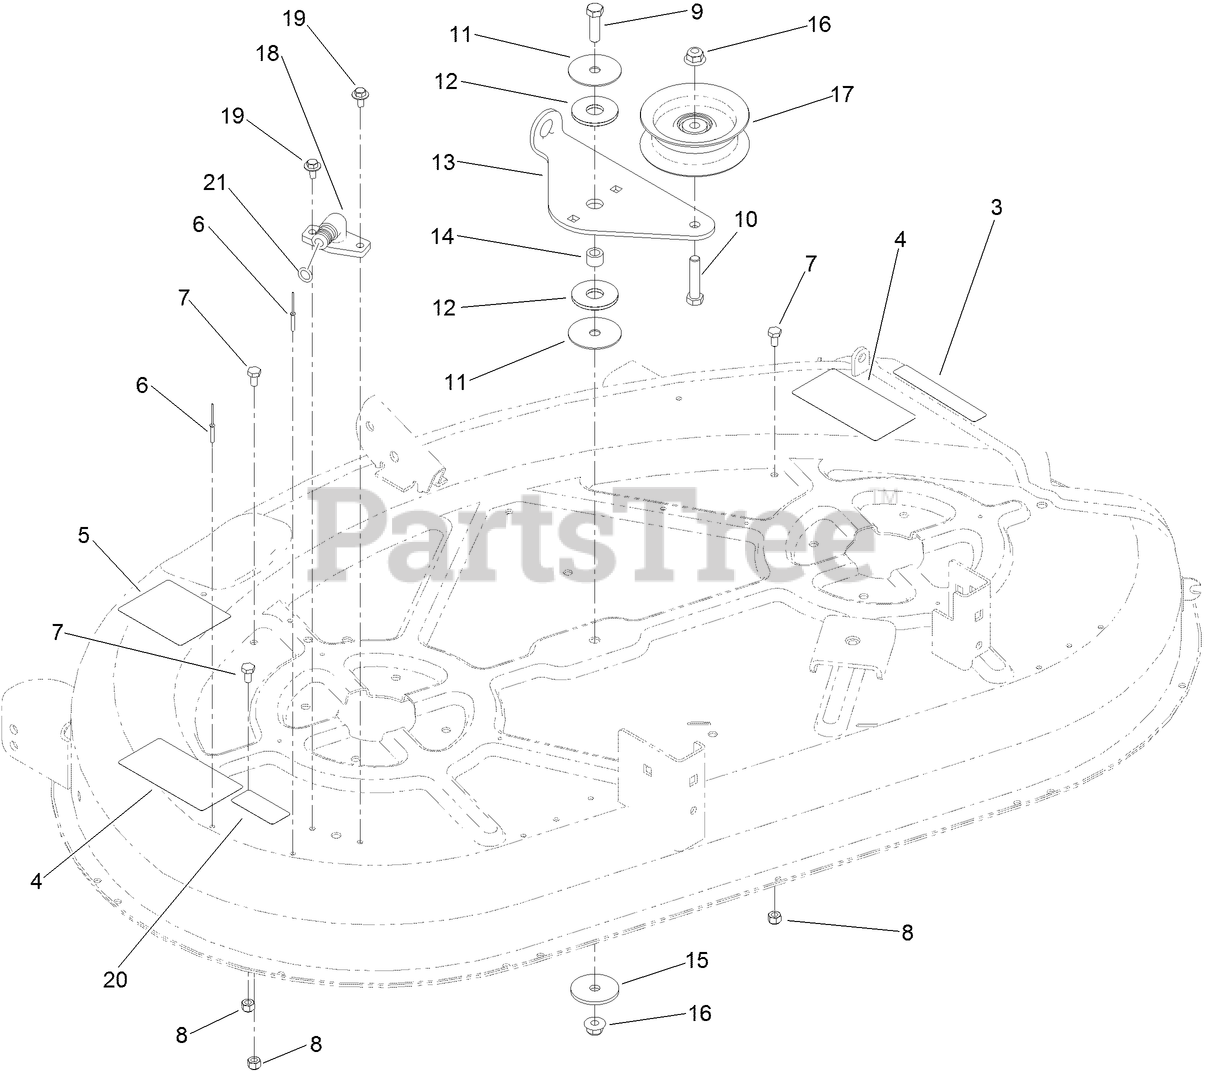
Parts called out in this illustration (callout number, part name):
3	DECAL-DANGER
4	DECAL-DANGER, DECK
5	DECAL-ROUTING, BELT
6	RIVET-BLIND
7	SCREW-HH
8	NUT-LOCK, NI
9	SCREW-HH
10	SCREW-HH
11	WASHER
12	WASHER-FRICTION, COMPOSITE
13	ARM-IDLER
14	SPACER
15	WASHER-REBOUND
16	NUT-HF, NI
17	PULLEY-IDLER, FLAT
18	FITTING-WASHOUT
19	SCREW-HHFTF
20	SERVICE DECAL
21	O-RING
